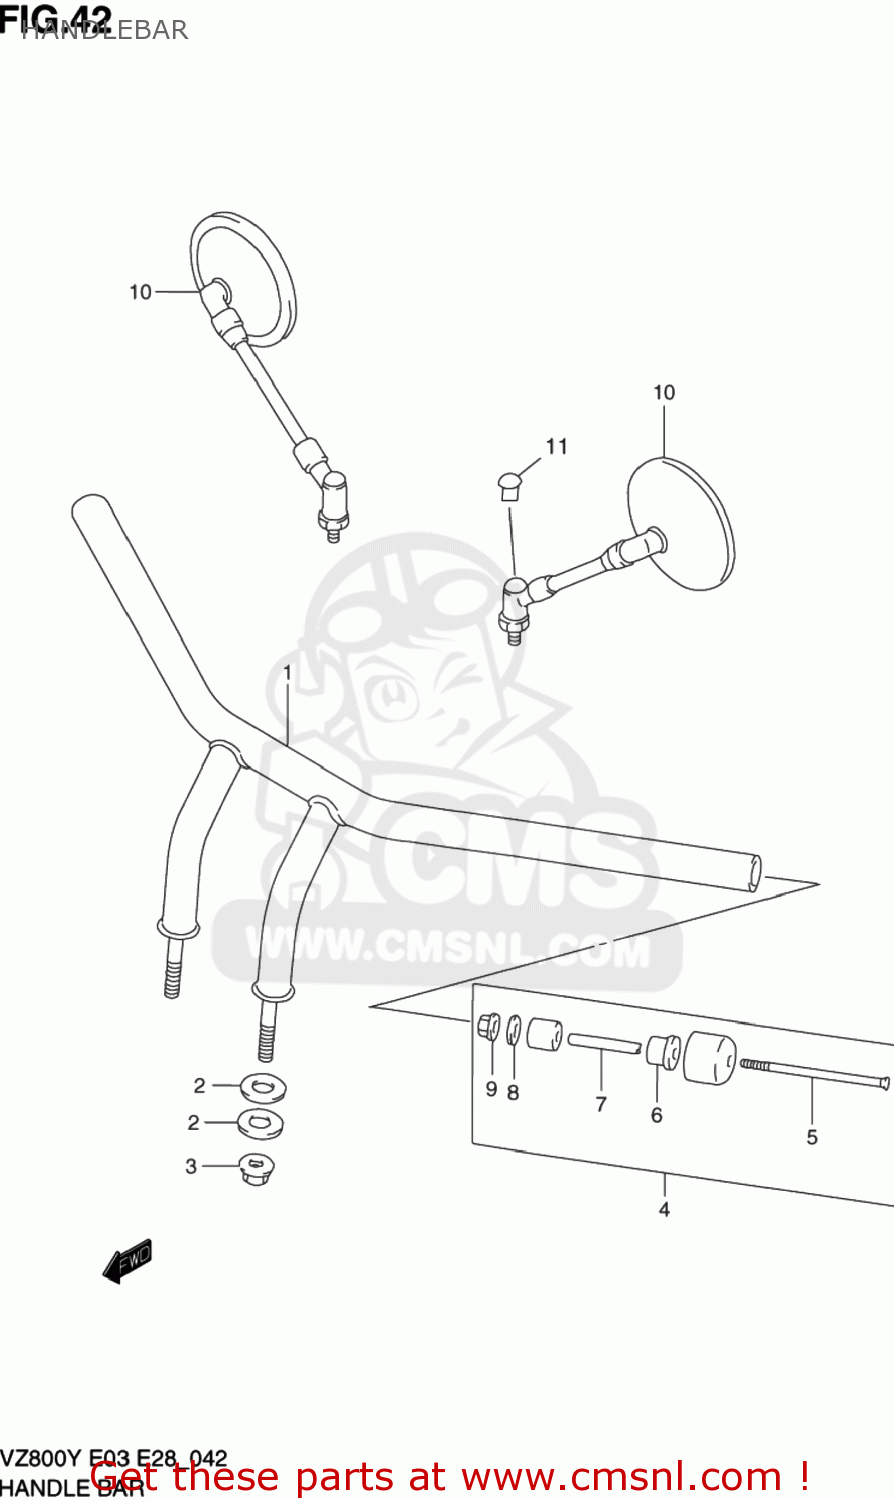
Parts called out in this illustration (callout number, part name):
1	HANDLEBAR
2	CUSHION,HANDLEBAR
3	NUT 12MM
4	BALANCER SET,HANDLEBAR
5	SCREW(6X110)
6	EXPANDER,HANDLE BALANCER NO.2
7	SPACER,EXPANDER
8	WASHER(6.5X18X2)
9	NUT
10	MIRROR ASSEMBLY,REAR VIEW
11	CAP
